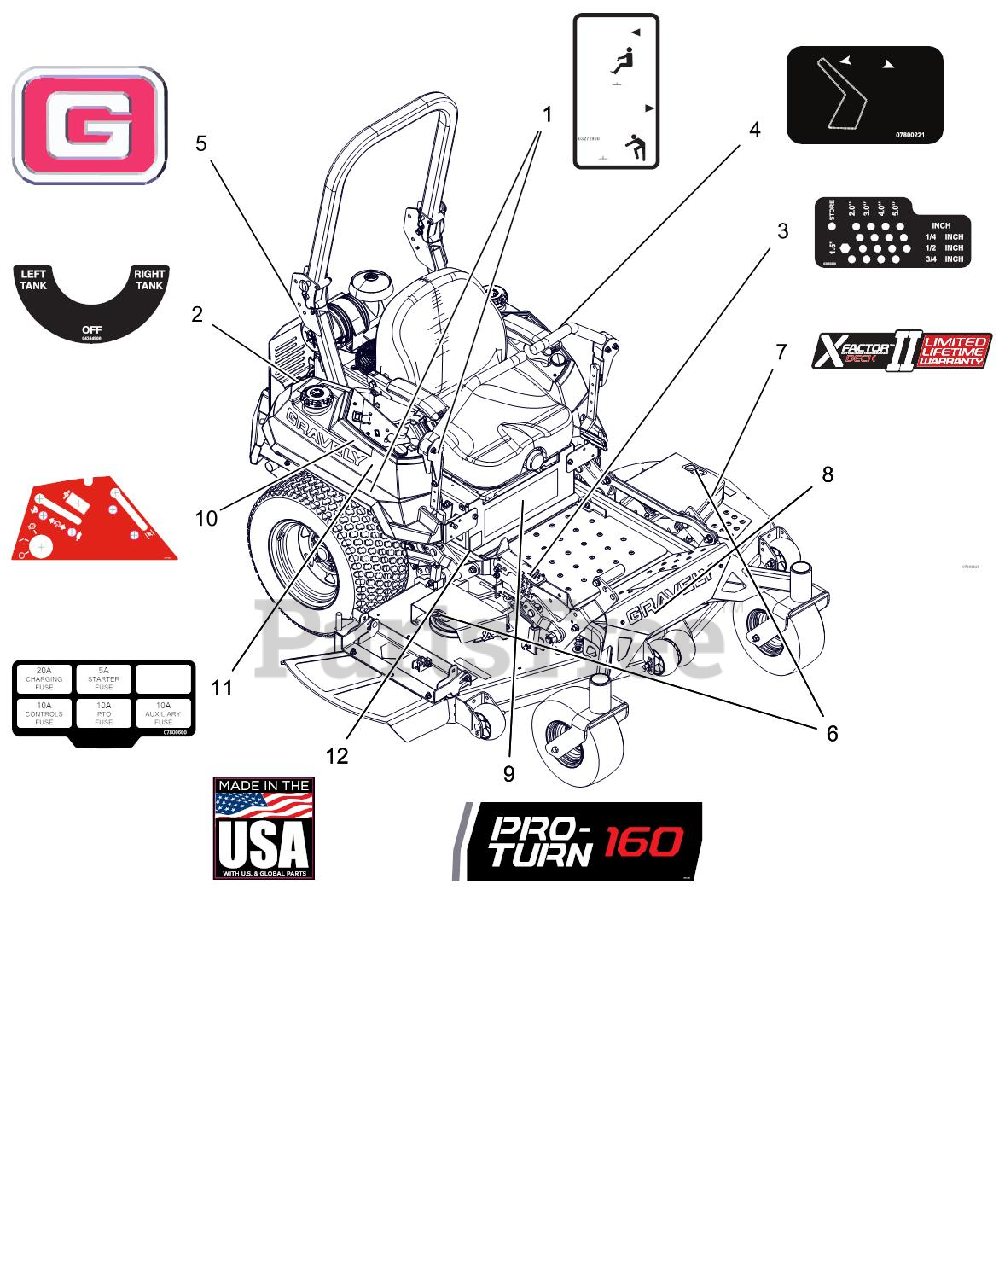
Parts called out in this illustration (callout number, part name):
1	DECAL, TRANSMISSION DISCONNECT
2	DECAL, FUEL VALVE
3	DECAL, HEIGHT OF CUT
4	DECAL - SEAT RELEASE
5	DECAL, GRAVELY BRAND
6	DECAL, 60"
7	DECAL, X-FACTOR DECK
8	DCL,BELT ROUTE-RH BK-SIDE IDLR
9	DECAL, PRO-TURN 160
10	DECAL, NON-EFI CONTROL PANEL
11	DECAL, FUSE BLOCK
12	DECAL, MADE IN USA
